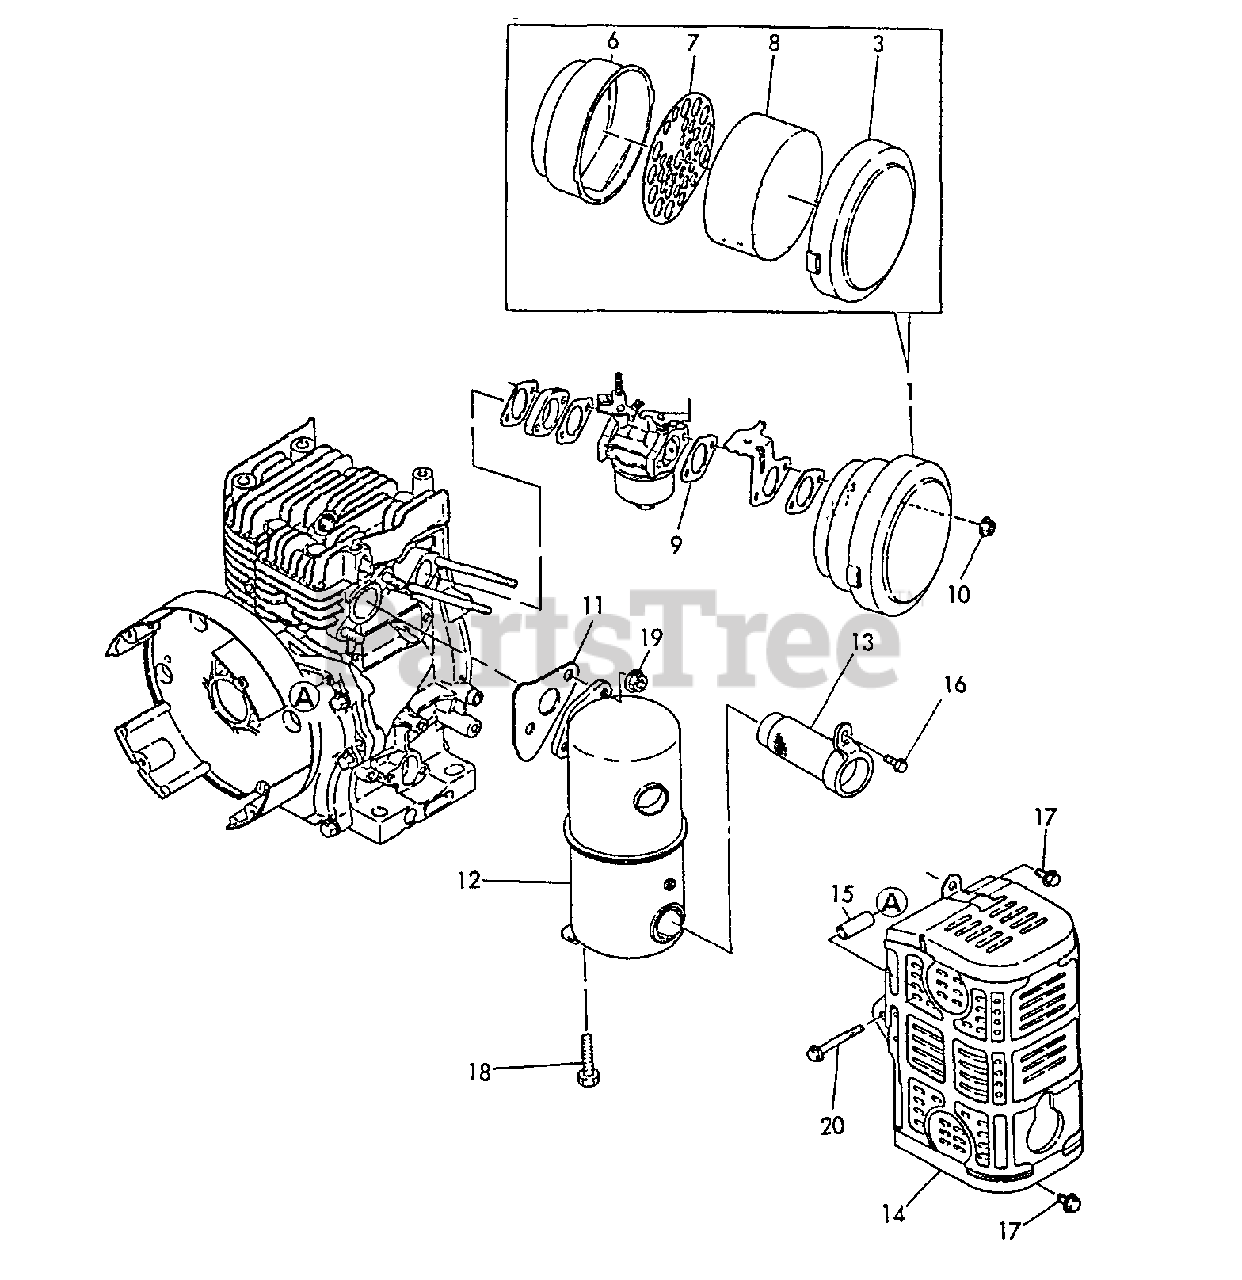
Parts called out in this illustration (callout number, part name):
1	AIR FILTER ASSY
3	COVER, AIR FILTER
6	CASE, AIR FILTER
7	PLATE, ELEMENT
8	FILTER, AIR
9	GASKET, INTAKE
10	U-NUT M6
11	GASKET, EXHAUST
12	MUFFLER
13	SCREEN, SPARK ARRESTER
14	COVER, MUFFLER
15	SPACER
16	BOLT - 6×10 -- PLATED
17	BOLT - 6×16
18	BOLT - 8×30 -- PLATED
19	U-NUT M8
20	BOLT - 6×55
